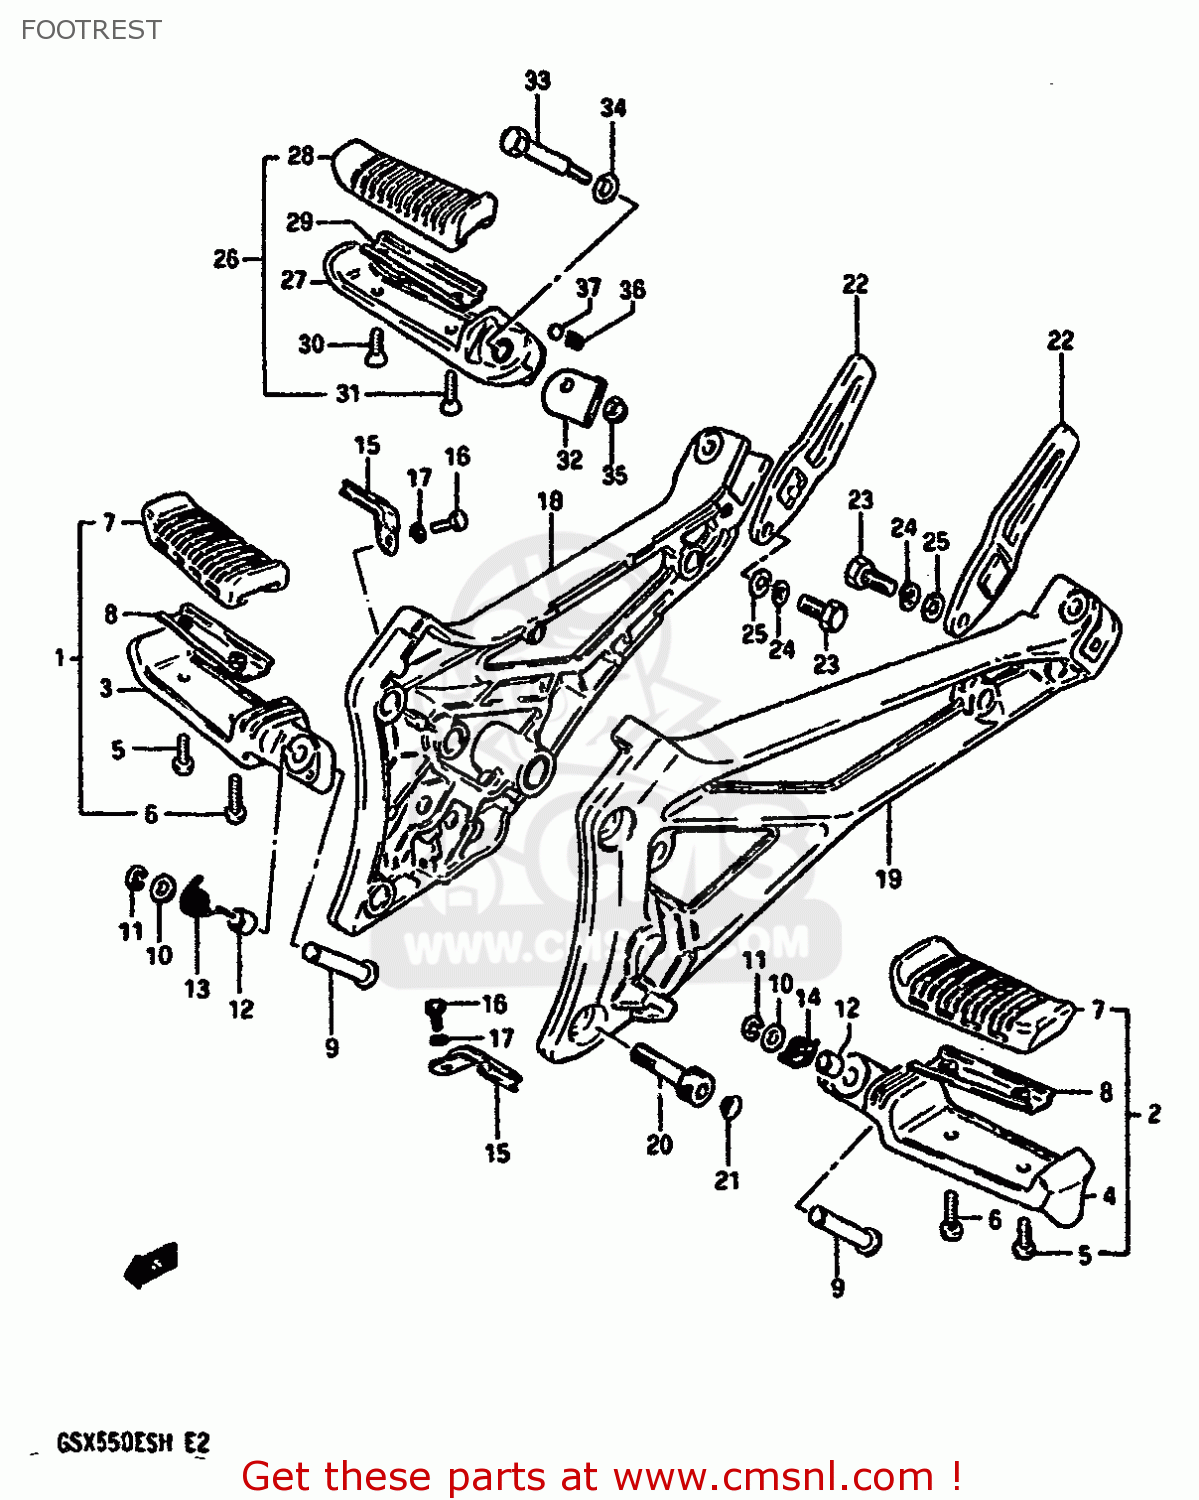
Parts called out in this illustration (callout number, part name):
1	FOOTREST ASSEMBLY,FRONT,RIGHT
2	FOOTREST ASSEMBLY,FRONT,LEFT
3	BAR,FRONT FOOTREST
4	FOOTREST,FRONT,LEFT
5	SCREW
6	SCREW
7	RUBBER,FOOTREST
8	PLATE,FR FOOTREST RUBBER
9	PIN
10	WASHER
11	E RING 6MM
12	BUSHING
13	SPRING
14	SPRING
15	CUSHION,FR FOOTREST
16	BOLT 5X10
17	LOCK WASHER
18	BRACKET,MUFFLER,RIGHT
19	BRACKET,MUFFLER,LEFT
20	BOLT 10X27
21	CAP
22	GUIDE,REAR FOOT
23	BOLT,8X16
24	LOCK WASHER
25	WASHER
26	FOOTREST ASSY,PILLION,R
27	BAR,PILLION FOOTREST,LEFT
28	RUBBER,RR FOOTREST
29	PLATE,RUBBER STOPPER
30	SCREW 5X12
31	SCREW 5X16
32	PLATE,SPRING STOP,R
33	BOLT
34	WASHER
35	NUT
36	SPRING
37	BALL
